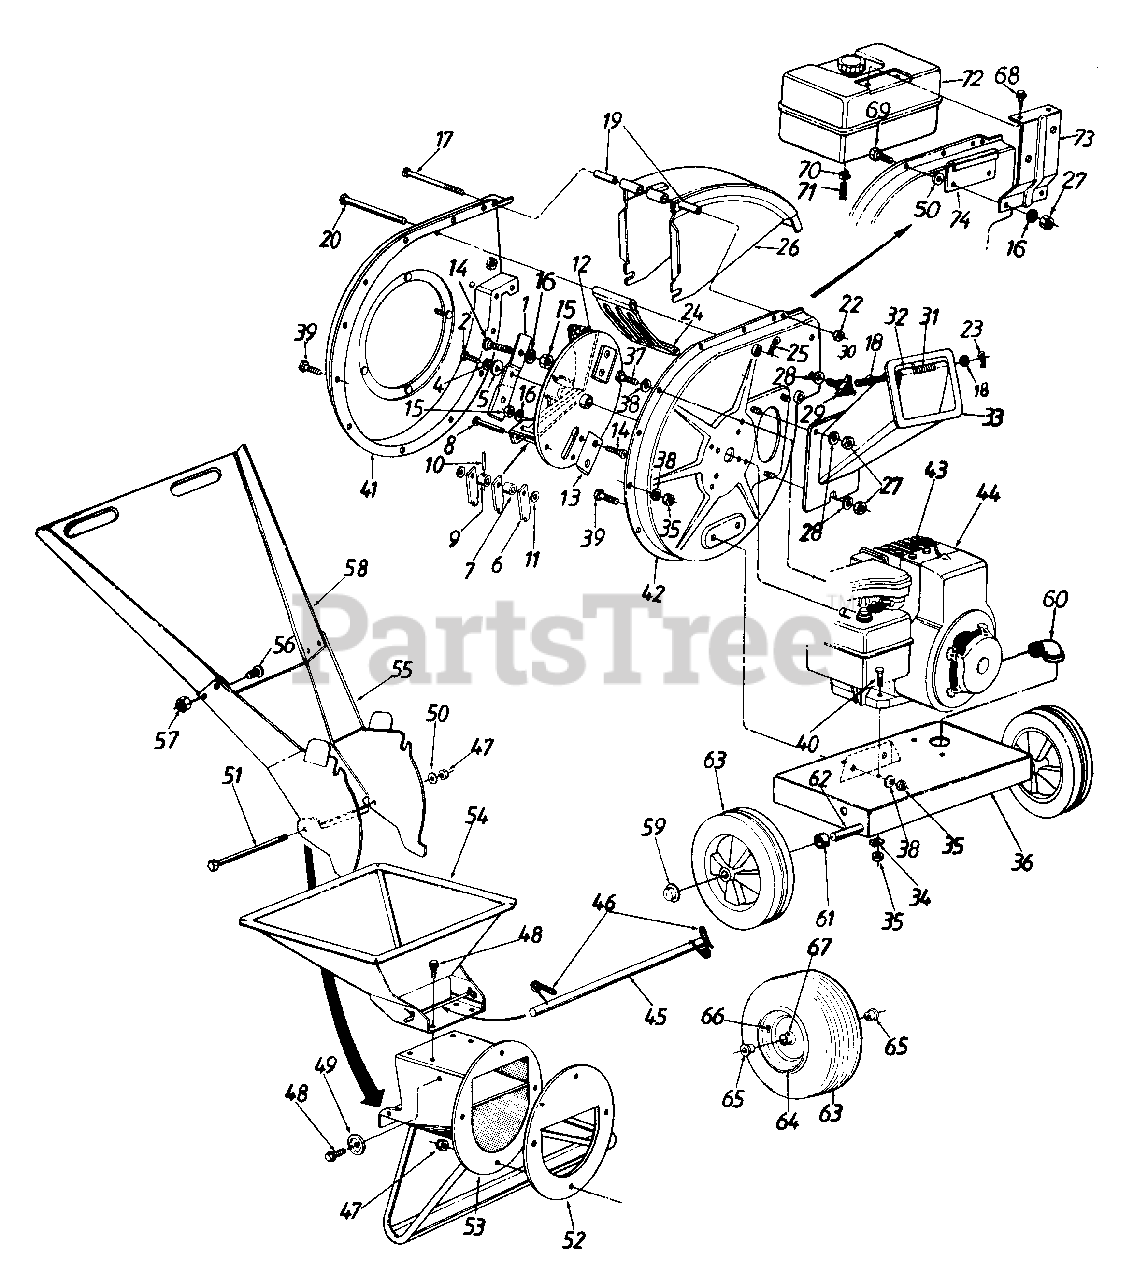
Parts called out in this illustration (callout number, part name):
1	Blade
2	Hex Patch Bolt 3/8-24 x 2.25" (Gr. 8)
4	L-Wash. 3/8" I.D. H.D.
5	FL-Wash. .406" I.D. x 1.25" O.D. Hdn.
6	Flail
7	Flail Spacer
8	Clevis Pin. 496" Dia.
9	Flail Spacer w/. 160" Dia. Hole
10	Spring Roll Pin 1.12" Lg.
11	FL-Wash. .531" I.D. x .94" O.D.
12	Impeller Ass'y. Comp.
13	Chipper Blade
14	Flat Hd. Scr. 5/16-24 x .75" Lg.
15	Hex Top L-Nut 5/16-24 (Gr. 5)
16	L-Wash. 5/16" I.D.
17	Hex Bolt 1/4-20 x 3.75" Lg.
18	FL-Wash. .281" I.D. x .5" O.D.
19	Chute Hinge Spacer 1.66" Lg.
20	Clevis Pin .5" Dia. x 4.62" Lg.
22	Hex Ctr. L-Nut 1/4-20 Thd.
23	Cotter Pin 3/32" x 5/8"
25	Internal Cotter Pin 3/8" Dia.
27	Hex Nut 5/16-18 Thd. (Gr. 5)
28	Bell-Wash. .345" I.D. x .88"
29	Hand Knob
30	Chipper Door Rod
31	Torsion Spring 1.14" Lg.
35	Hex Nut 5/16-18 Thd. (Gr. 5)
38	L-Wash. 5/16" I.D.
39	Hex Bolt 5/16-18 x .75" Lg. (Gr. 5)
40	Hex Bolt 5/16-18 x 1.5" Lg. 5 H.P. & 8 H.P. Tec.
44	Engine
45	Release Bar
46	Torsion Spring 1.06" Lg.
47	Elastic Lock Nut 5/16-18 Thd.
48	Hex Wash. Hd. Self-Tap Scr. 5/16-18 x .75" Lg.
49	Stop Washer
50	FL-Wash. 5/16" I.D.
51	Hex Bolt 5/16-18 x 8.38" Lg.
57	Hex L-Nut 1/4-20 Thd.
60	Drain Elbow 5 HP B&S
61	Spacer .64" I.D. x .38" Lg.
62	Shredder Axle
63	Wheel Ass'y. Comp. Plastic - 10 x 2.5
64	Rim Only
65	Flange Bearing .632" I.D.
66	Air Valve
67	Grease Fitting
68	Hex Hi-Low Scr. 1/4 x .75"
69	Hex Bolt 5/16-18 x .88" Lg.
70	Hose Clamp
71	Fuel Line - 7 In.
72	Fuel Tank Ass'y. Comp.
